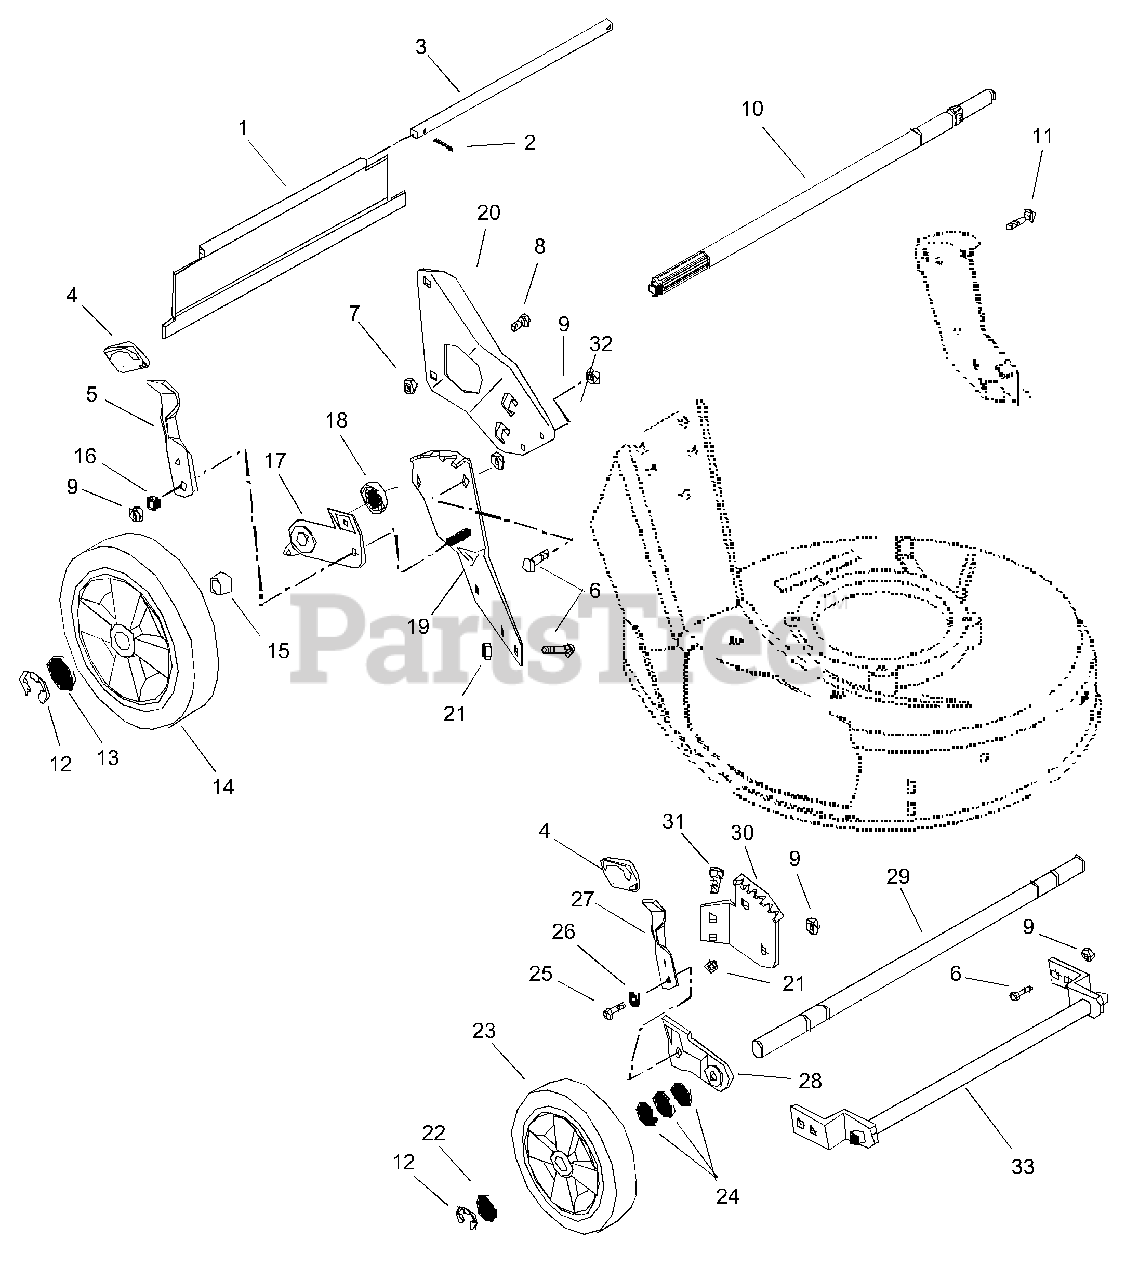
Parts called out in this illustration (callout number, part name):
1	REAR PROTECTIVE GUARD, PUSH
1	REAR PROTECTIVE GUARD, S.P.
2	@PIN-CTR .06X.50 EXTPRSQCT YWZ
3	ROD
5	HEIGHT ADJUSTMENT LEVER
6	@BLT-RHDSSQNK .31-18X.62 G5YZ
7	@NUT-LK-CTR .38-16 YWZC
8	HANDLEBAR STUD
9	@NUT-LK-CTR .31-18 YWZC
10	REAR AXLE,5/8 DIA
10	REAR AXLE-PUSH MOWER MM
10	REAR AXLE-PUSH MOWER
11	BLT-RDHDSQNK .31-18X1.0 SHTYZ
12	RG-RTNG-EXT .500X.042 (E)
13	WSHR-FL-STL .505X.880X.072 YWZ
14	LH WHEEL
14	RH WHEEL
14	TIRE 10X1.75
14	10 1/2 TIRE SKIN
15	SPACER TUBE,PUSH LH
15	SPACER TUBE PUSH RH
15	SPACER TUBE, SELF PROPEL
16	BSHG-FLG .32X.500X.344X.880
17	REAR BRACKET & BEARING ASSEMBL
17	R.H. REAR ADJUSTOR BRACKET
17	L.H. REAR ADJUSTOR BRACKET
17	REAR ADJUSTMENT BRACKET L.H.
17	REAR BRACKET & BEARING ASSY RH
18	BRG-BALL .625X1.383X.50
19	QUADRANT, REAR - L.H.
19	REAR QUADRANT, R.H.
20	RH HANDLEBAR MTG. BRKT.
20	RH HANDLEBAR MOUNT WELDMENT
20	LH HANDLEBAR MTG. BRKT.
20	LH HANDLEBAR MOUNT BRKT WELDM
21	@NUT-SPNLK-FLG .312-18 YWZC
22	WSHR-FL-STL .505X.880X.072 YWZ
23	WHEEL
23	TIRE 7X1.50
24	WSHR-FL-STL .52X.827X.062 YWZC
25	@BLT-HEX .31-18X1.00 GR5 YWZC
26	BSHG-FLG .32X.500X.344X.880
27	FRONT HEIGHT ADJUSTMENT LEVER
28	LEFT ADJUSTOR BRACKET ASSEMBLY
28	RIGHT ADJUSTOR BRACKET ASSEMBL
28	RH ADJUSTER BRACKET
28	LH ADJUSTER BRACKET
29	FRONT AXLE
30	FRONT QUADRANT, RH
30	FRONT QUADRANT, LH
31	@BLT-RDHDSQNK .31-18X.50 G5YZ
32	@NUT-LK-NYL .312-18 YWZC
33	DETHATCHER RETAINER WELDMENT
